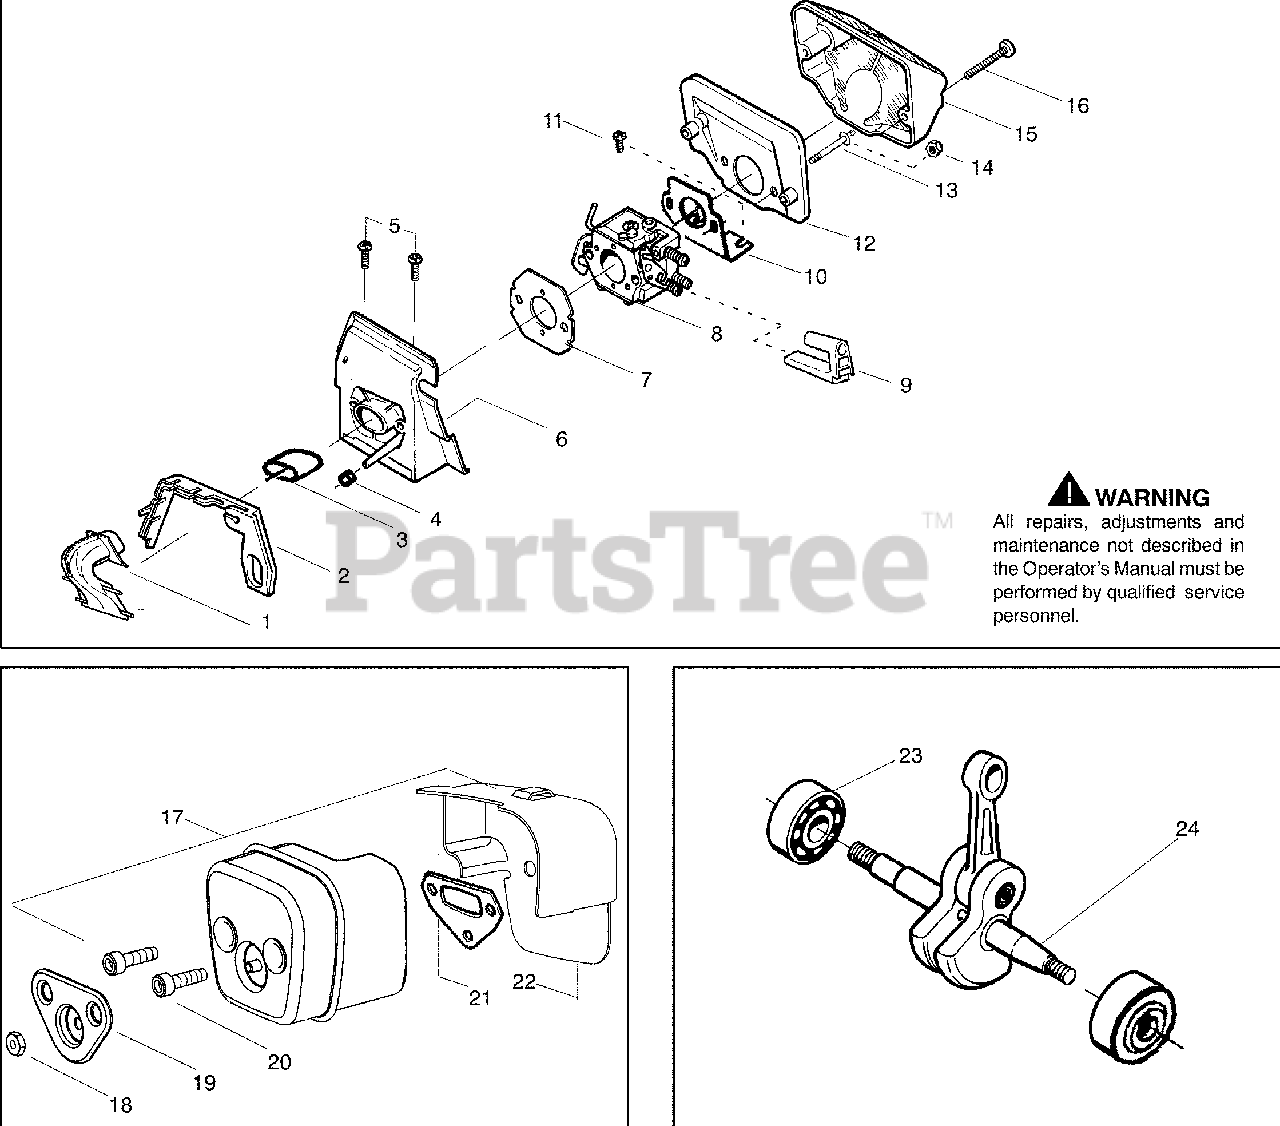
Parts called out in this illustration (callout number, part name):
1	Assy--Turbo Air Cleaner
2	Seal -- Turbo Clean
3	Sleeve--Intake
4	Seal--Impulse
6	Adapter -- Carb.
7	Gasket--Carburetor
8	Carburetor
9	Grommet--Final
10	Plate -- Support
12	Air Filter -- Bottom
13	Stud -- Carb.
15	Air--Filter -- Top
17	Kit--Muffler
18	Nut--Brass
19	Cover--Bolt
20	Bolt--Muffler
21	Gasket--Muffler
22	Backplate--Muffler
23	Assy. --Bearing and Seal
24	Assy--Crankshaft & Rod
